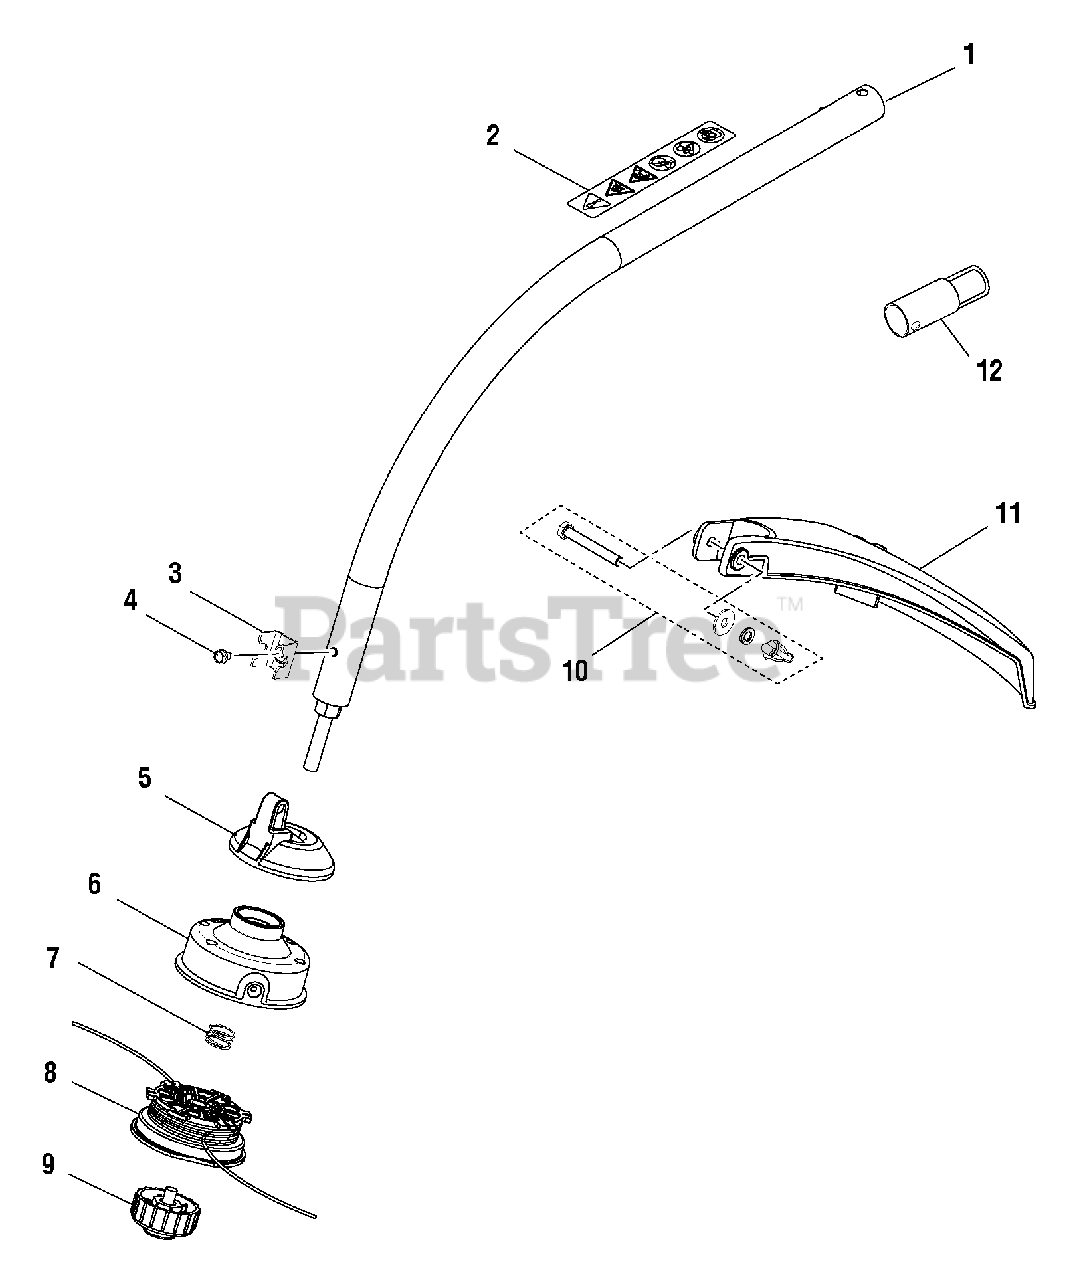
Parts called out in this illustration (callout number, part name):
1	CURVED SHAFT ASSEMBLY
2	WARNING LABEL
3	CLAMP
4	SCREW (#10-24 X 3/8 in. HEX WASHER HEAD)
5	GRASS SHIELD
6	TRIMMER HEAD
7	COMPRESSION SPRING
8	SPOOL WITH LINE (.095)
9	RETAINING CAP, LEFT-HANDED THREAD
10	FASTENER PARTS KIT
11	GRASS DEFLECTOR ASSEMBLY
12	HANGER CAP
